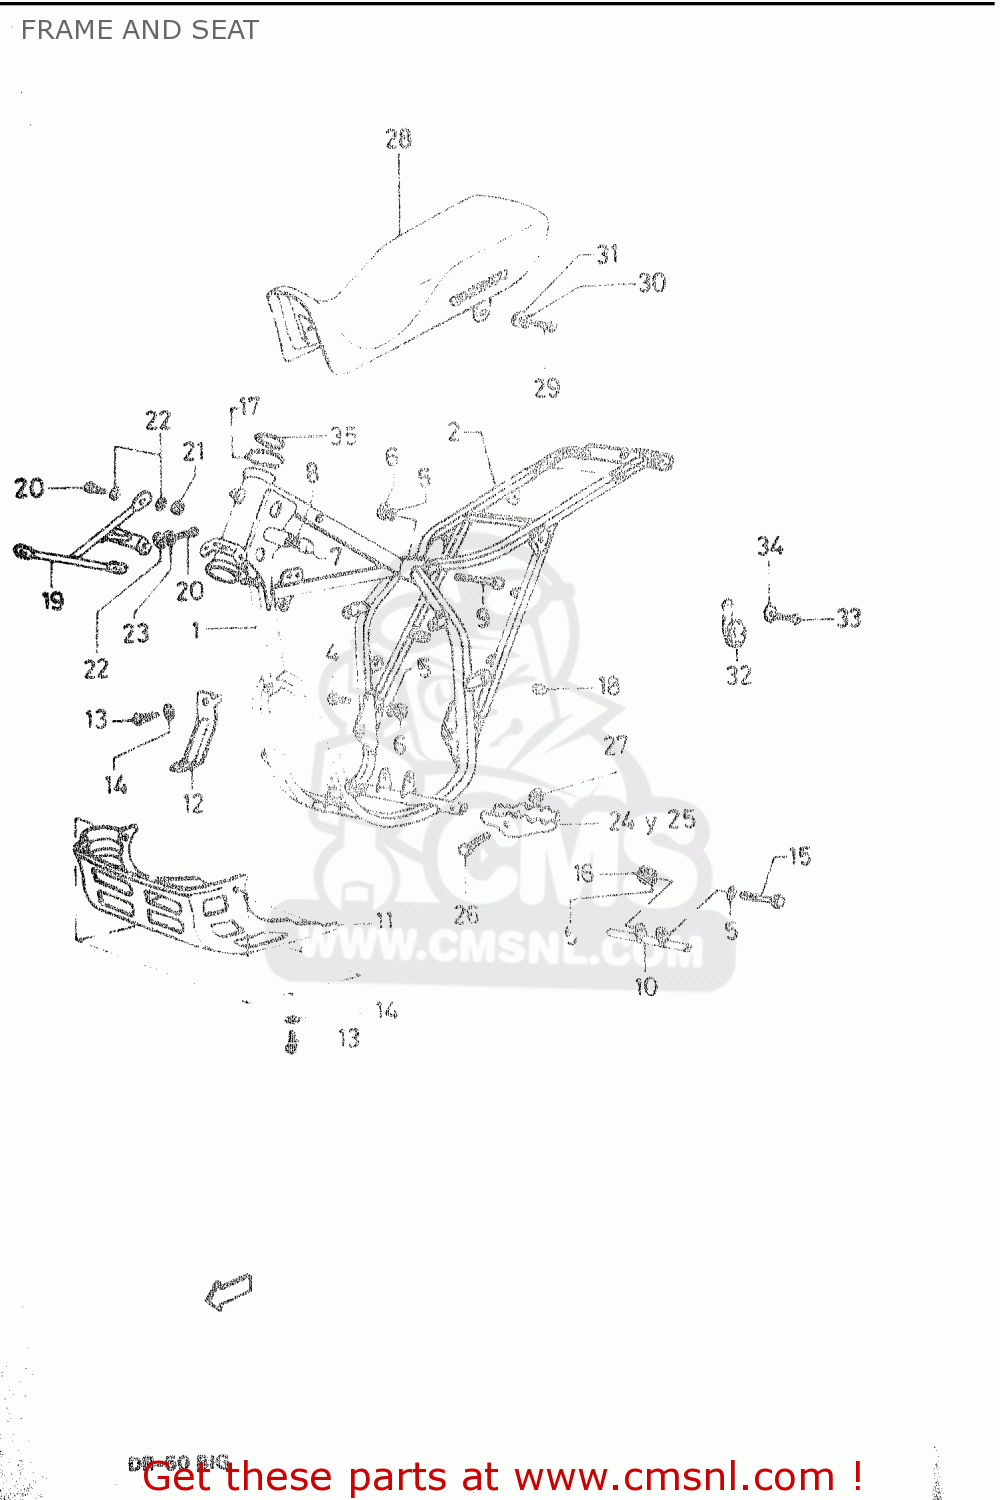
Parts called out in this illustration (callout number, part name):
1	FRAME (BLUE)
2	FRAME, REAR (BLUE)
4	SCREW M8X20 DIN 933/8G
5	WASHER B8 DIN 125
6	NUT
7	CUSHION
8	WASHER
9	SCREW M8X100 DIN 931
10	BRACKET SET, CRANKASE
11	PROTECTOR, ENGINE (BLUE)
12	PLATE, PROTECTOR COOLING
13	SCREW M5X12 DIN 7985/N
14	WASHER 5 DIN 9021
15	SCREW M8X1X80 DIN 960
16	NUT M8X1 DIN 985
17	BALL
18	CUSHION
19	BRACKET, COWLING FRONT (BLUE)
20	SCREW M5X12 DIN 7985
21	NUT
22	WASHER B135 DIN 125
23	WASHER A5 DIN 6798
24	FOOTREST, FRONT RH
25	FOOTREST, FRONT RL
26	SCREW M6X30 DIN 931
27	NUT M6 DIN 985
28	SEAT SET (BLUE)
29	SCREW M6X15 DIN 7985/N
30	WASHER A6 DIN 137
31	WASHER B6 DIN 125
32	HORN ASSY
33	SCREW M6X16 DIN 7985/N
34	WASHER 6 DIN 6798
35	O-RING
